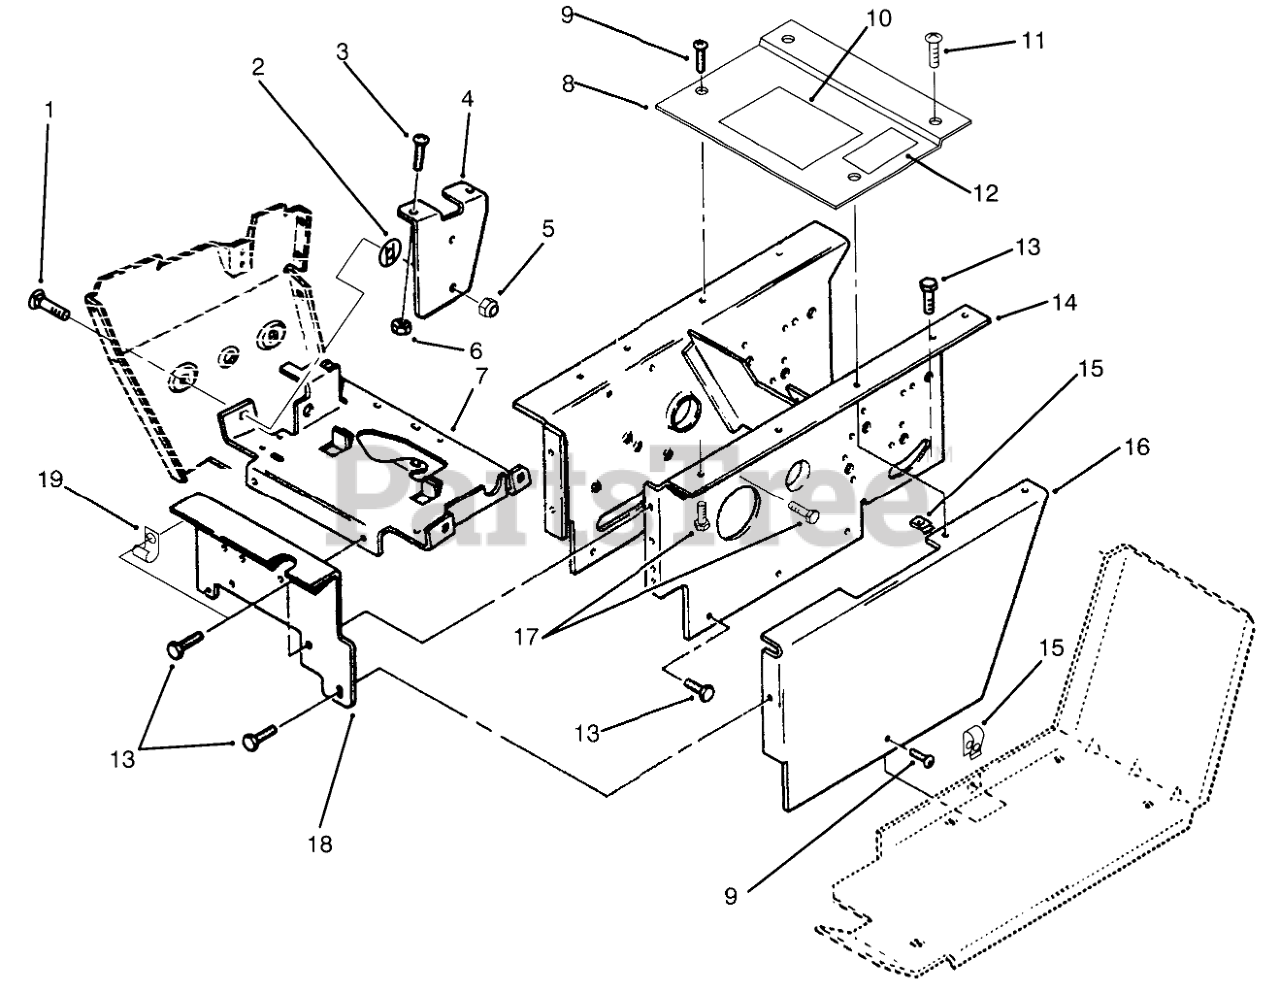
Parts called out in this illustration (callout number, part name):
1	BOLT-CARR
2	NUT-PUSH
3	SCREW-HH
4	Bracket-Holder
5	NUT-LOCK, NI
6	Nut
7	WLD-SUPPORTB
8	Plate-Hoodstand,Top (Incl. Ref.#10)
9	Screw
10	DECAL-DANGER
11	Screw
12	DECAL-PARKING BRAKE
13	SCREW
14	Hoodstand
16	Cover-Side LH
17	SCREW-HH
18	Plate-Front
19	CLIP
